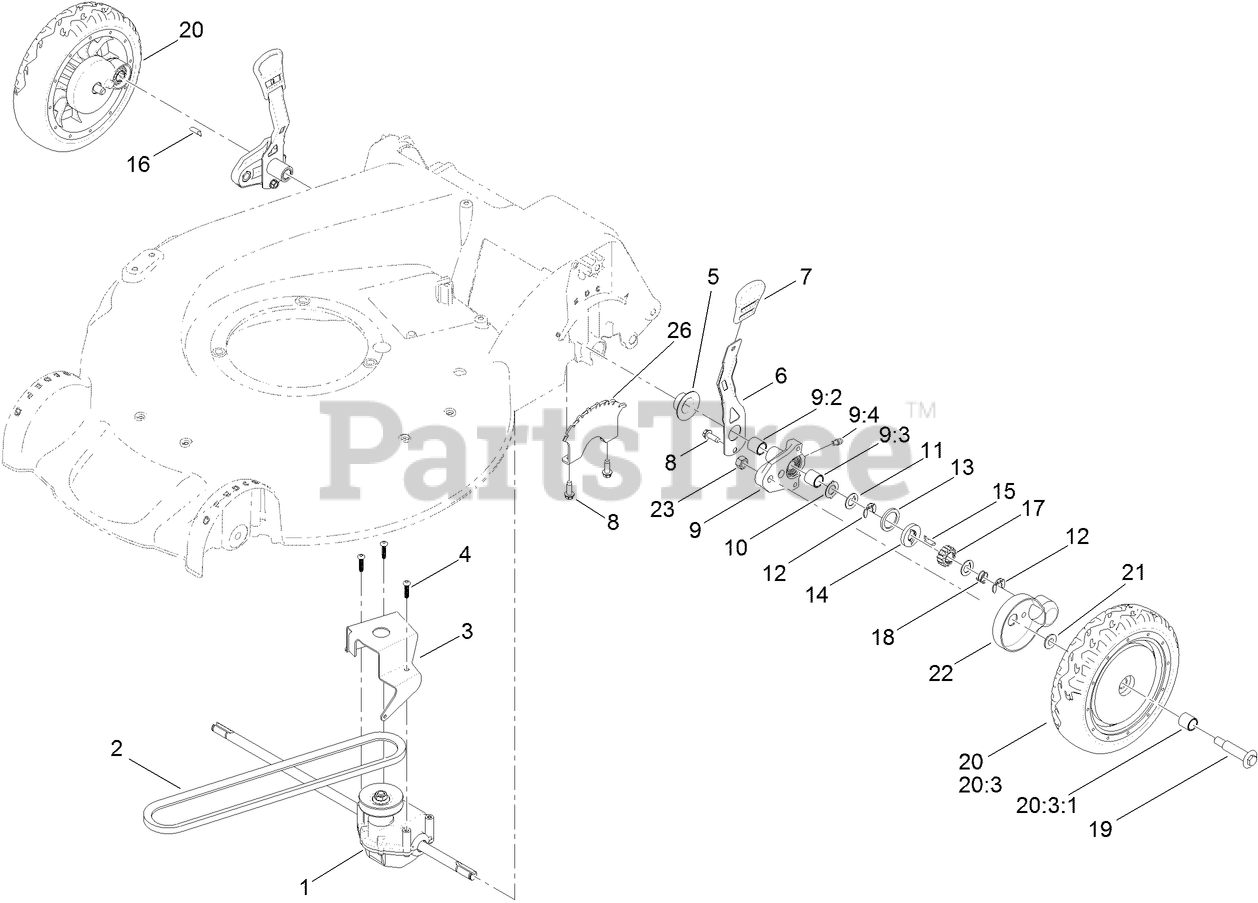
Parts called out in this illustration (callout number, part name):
1	TRANSMISSION ASM
2	V-BELT
3	BRACKET-TRANSMISSION
4	SCREW-PLASTITE
5	CAP-END
6	ARM-SPRING
7	KNOB-HOC
8	SCREW-HWHTF
9	PIVOT ARM ASM
9:2	BUSHING
9:3	BUSHING
9:4	FITTING-GREASE
10	WASHER-ARM, PIVOT
11	WASHER-THRUST, KEYED
12	RING-RETAINING,CLIP
13	RING-FRICTION
14	WASHER-CLUTCH
15	KEY-ROCKING, LH
16	KEY-ROCKING, RH
17	GEAR-PINION
18	SPRING-COMPRESSION
19	BOLT-SHOULDER
20	WHEEL GEAR ASM
20:3	Loose Parts Package
20:3:1	BUSHING
21	SPACER-COVER, WHEEL
22	COVER-WHEEL
23	LOCKNUT
26	PLATE-HOC
